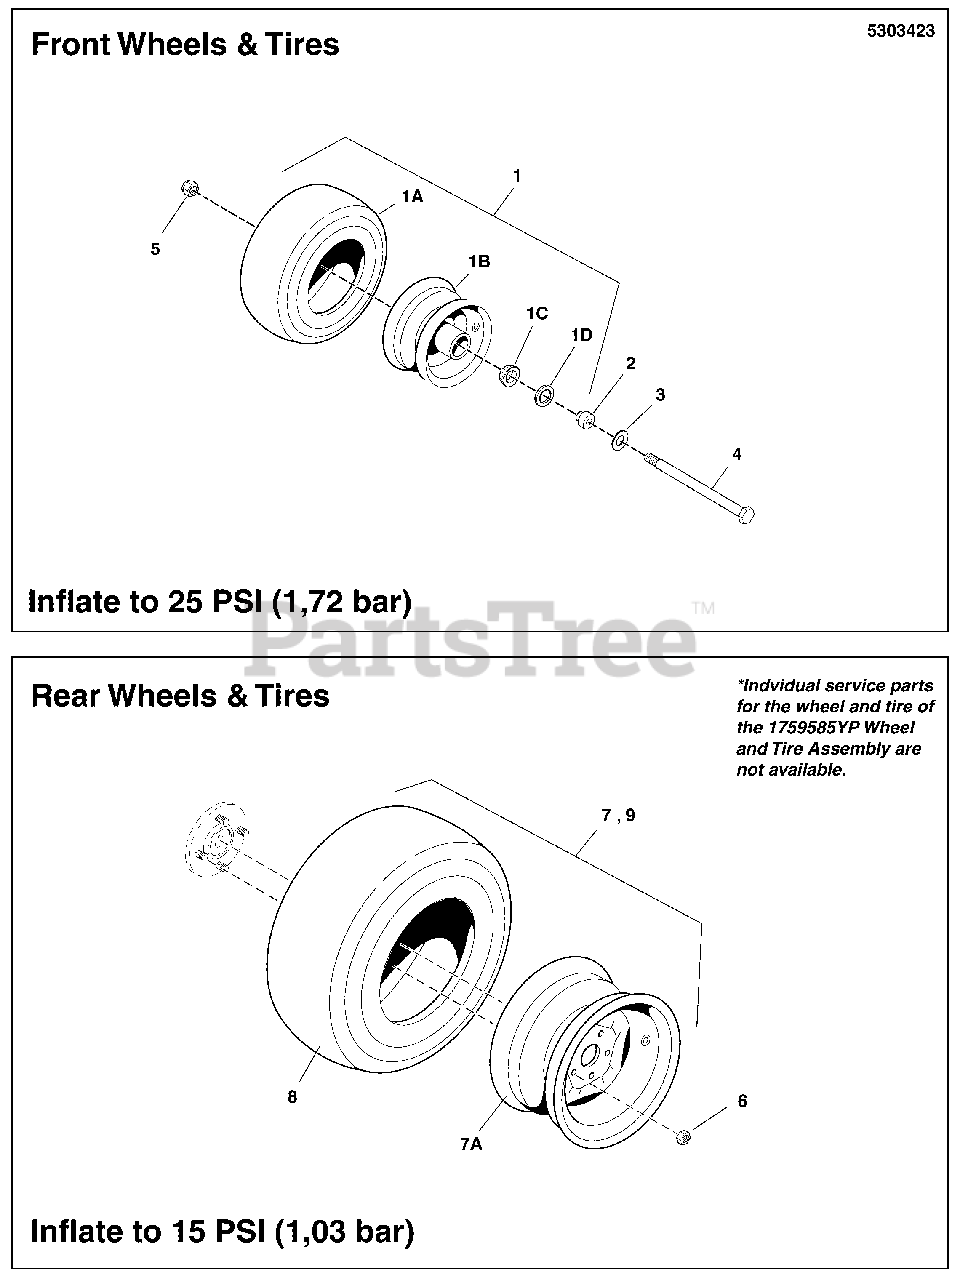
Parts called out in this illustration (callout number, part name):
1	TIRE, CASTER, 13 X 5.00-6
1A	TIRE ONLY (SV)
1B	WHEEL ASSY, 13 X 5 X 6, SILVER (SV)
1C	BEARING, TAPERED CONE
1D	SEAL, GREASE
2	ADAPTER, CASTER AXLE, CZ
3	WASHER, 1/2 SAE
4	BOLT, 1/2-13 X 8 GD5 YZ
5	NUT, 1/2-13 HEX NYLOCK FLANGE
6	NUT, 1/2-20, FOR WHEEL BOLT SILVER
7	TIRE/WHEEL ASM, 20X 10-8, TURF MASTER
7A	WHEEL, 8 X 6.331.29" NEG OFFSET, 4/4 BOLT PATTERN (SV)
8	TIRE, 20 X 10 - 8, TURF MASTER (SV)
9	WHEEL AND TIRE ASSY, 20X10-8 (K505)
